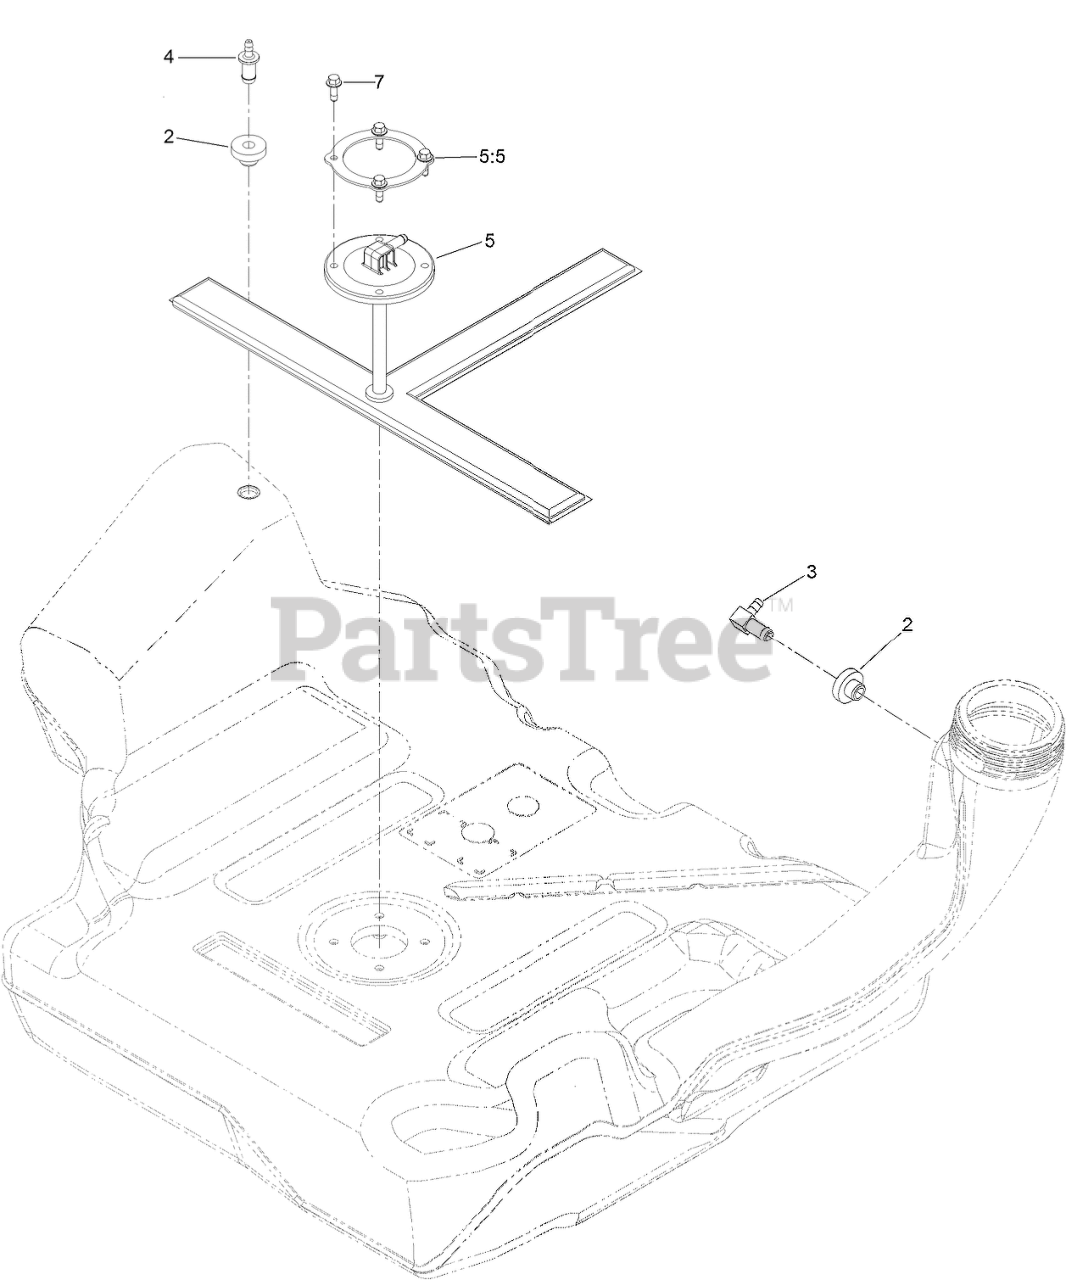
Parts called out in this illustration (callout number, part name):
2	BUSHING
3	FITTING-90 DEG
4	FITTING-ORIFICE, STRAIGHT
5	PICKUP-FUEL
5:5	RING-RETAINER
